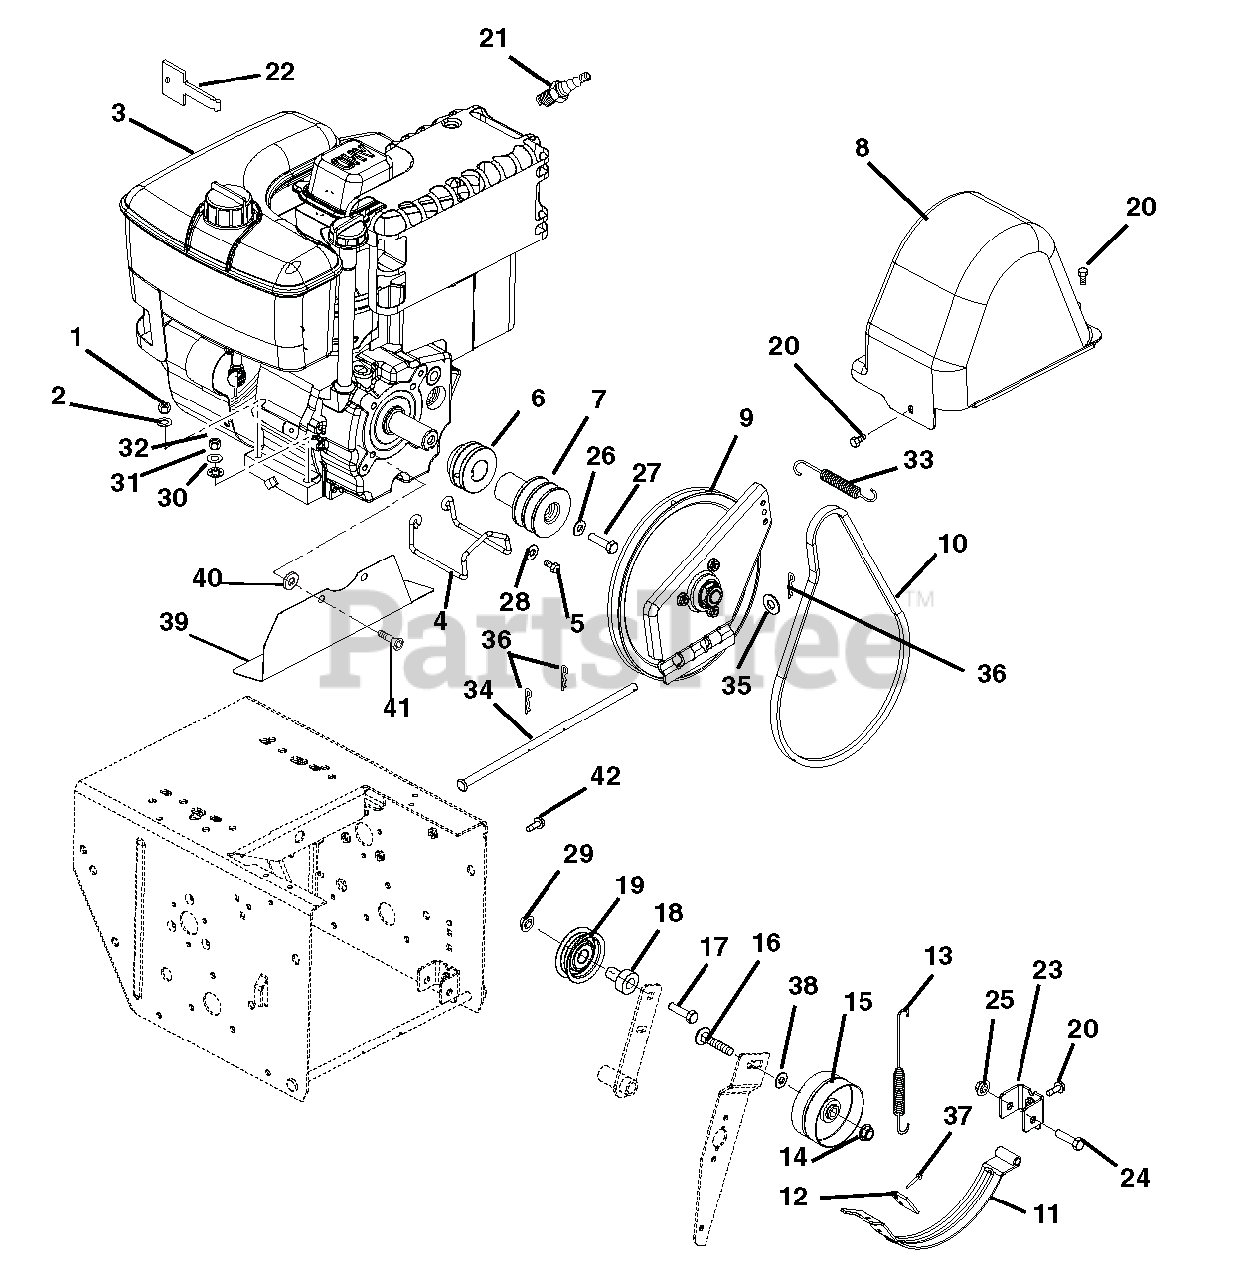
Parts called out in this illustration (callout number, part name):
1	@NUT-HEX .31-18 YWZC
2	WSHR-LK .312X.097 HVY YWZC
3	ENGINE, 11.5HP OHV TEC. 120V
3	ENGINE, 11.5HP OHV TEC. 240V
3	ENGINE, 13HP OHV TEC. 240V
3	ENGINE, 13HP OHV TEC. 12V
3	ENGINE, 9.5HP TEC OHV 120V 3/5
3	ENGINE, 10HP TEC OHV 120V 18W
3	ENGINE, 13HP OHV TEC. 120V
3	ENGINE, 9.5HP TEC OHV 220V 3/5
4	FINGER, BELT
5	BLT-HEX .31-24X.75 YWZC GR5
6	SHEAVE, DRIVE
7	SHEAVE, ATTACHMENT 2 GROOVE
7	SHEAVE, ATTACHMENT
8	COVER, BELT
9	PLATE, SWING ASSEMBLY-DEEP
10	V-BELT, 3L-WRAPPED
11	ARM, BRAKE-ATTACHMENT
12	PAD, BRAKE
13	SG-TENS .056X.60X4.40
14	@NUT-LK-TOP-FLG .38-16 YWZC
15	IDLER-FLAT 2.75X.38 PAINTED
15	IDLER, FLAT-3.00
16	@BLT-RHDSSQNK .38-16X1.75 G5YZ
16	@BLT-HEX .38-16X1.50 GR5 YWZC
17	@BLT-HEX .31-18X1.25 GR5 YWZC
18	SPCR, BRG .315X.50X.688X.281
19	IDLER
20	SCR-TAP .25-20X.50 HWH TR YWZ
21	PLUG, SPARK
22	KEY, PUSH/PULL - TECUMSEH
23	PIVOT, BRAKE
24	@BLT-HEX .31-18X2.00 GR5 YWZC
25	@NUT-LK-TOP-FLG .31-18 YWZC
26	@WSHR-LK .38X.094 REG YWZC
27	BLT-HEX .38-24X2.25 YWZC GR5
27	BLT-HEX .38-24X2.0 YWZC
28	WSHR-LK .312X.097 HVY YWZC
29	@NUT-LK-TOP-FLG .31-18 YWZC
30	WSHR-LOCK INT .31 YWZC
31	@WSHR-FL-STL.344X.688X.065YWZC
32	@NUT-LK-CTR .31-18 YWZC
33	SG-TENS .048X.50X2.8
34	PIN, PIVOT
35	@WSHR-FL-STL.406X.812X.065 YWZ
36	PIN-HAIR, ENDRIES #25 YWZC
37	RVT-POP .187 YZ
38	@WSHR-FL-STL.38X.875X.083 YWZC
39	BAFFLE, ENGINE
39	BAFFLE, ENGINE - 13HP TECUMSEH
40	WSHR-FL-STL .536X1.07X.109 YZ
41	SCR-MCH.31-24X.75FLCTRSK EP80
42	@SCR-TAP .25-20X1.50 HWH TR YZ
